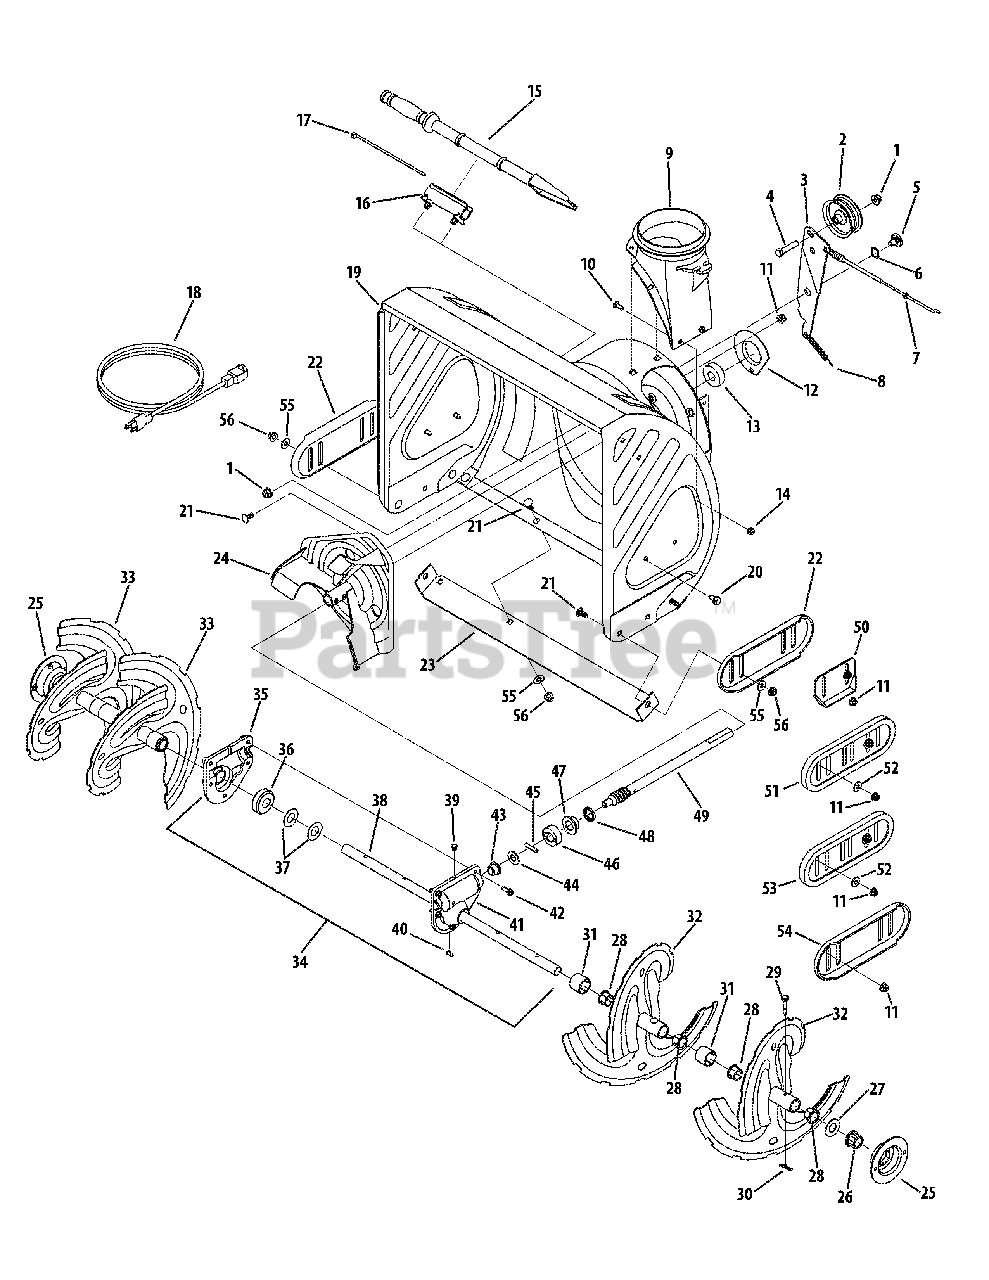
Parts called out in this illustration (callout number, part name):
1	Flange Lock Nut, 3/8 -16
2	Idler Pulley
3	Auger Idler Bracket w/ Brake
4	Hex Bolt, 3/8 -16 x 1.75
5	Shoulder Screw, .625 x .17 x 3/8 -16
6	Wave Washer, .625 x .885 x .015
7	Clutch Cable
8	Extension Spring, .38 OD x 3.6
9	Chute Adapter, 5.0
10	Carriage Screw, 1/4-20 x .75
11	Flange Lock Nut, 5/16-18
12	Bearing Housing
13	Ball Bearing, .75 ID x 1.85 OD
14	Flange Lock Nut, 1/4-20
15	Cleanout Tool
16	Cleanout Tool Mount
17	Cable Tie, 5/16 x .05 x 7.4
18	Extension Cord, 3-Prong
19	Auger Housing, 26"
20	Hex Washer Screw, 5/16-18 x .750
21	Carriage Bolt, 5/16-18 x .750
21	Carriage Bolt, 5/16-18 x 1.00
22	Deluxe Stainless Skid Shoe
23	Stainless Steel Shave Plate, 26"
24	Impeler Assembly
25	Bearing Housing
26	Hex Flange Bearing
27	Flat Washer, .76 x 1.49 x .06
28	Flange Bushing .800 ID x .910 OD
30	Bow-Tie Cotter Pin
31	Spacer, 1.25 OD x .75 ID x 1.00
32	Spiral Assembly, LH
33	Spiral Assembly, RH
34	Gearbox Assembly, 26"
35	Housing Assembly, RH
36	Worm Gear, 2OT
37	Flat Washer, .760 ID x 1.50 OD
38	Auger Axle, 26"
39	Plug, 1/4 x .437
40	Hi-Pro Key, 3/16 x 3/8
41	Housing Assembly, LH
42	Hex Washer Screw, 1/4-20 x .750
43	Flange Bearing, .50 ID x .75 OD x .59
44	Flat Washer, .51 x 1.12 x .06
45	Dowel Pin, .25 OD x 1.25
46	Thrust Collar, .756 ID x .600
47	Flng. Bearing, .75 ID x 1.00 OD x .59
48	Oil Seal, .75 x 1.131 x .188
49	Worm Shaft, .75 OD
51	Polymer Skid Shoe
51	Standard Polymer Reversible Shoe Kit
52	Flat Washer, .349 x .879 x .063
53	Deluxe Polymer Skid Shoe
53	Deluxe Polymer Reversible Shoe Kit
54	Deluxe Skid Shoe
55	Bell Washer, .340 x .872 x .060
56	Hex Nut, 5/16-18
